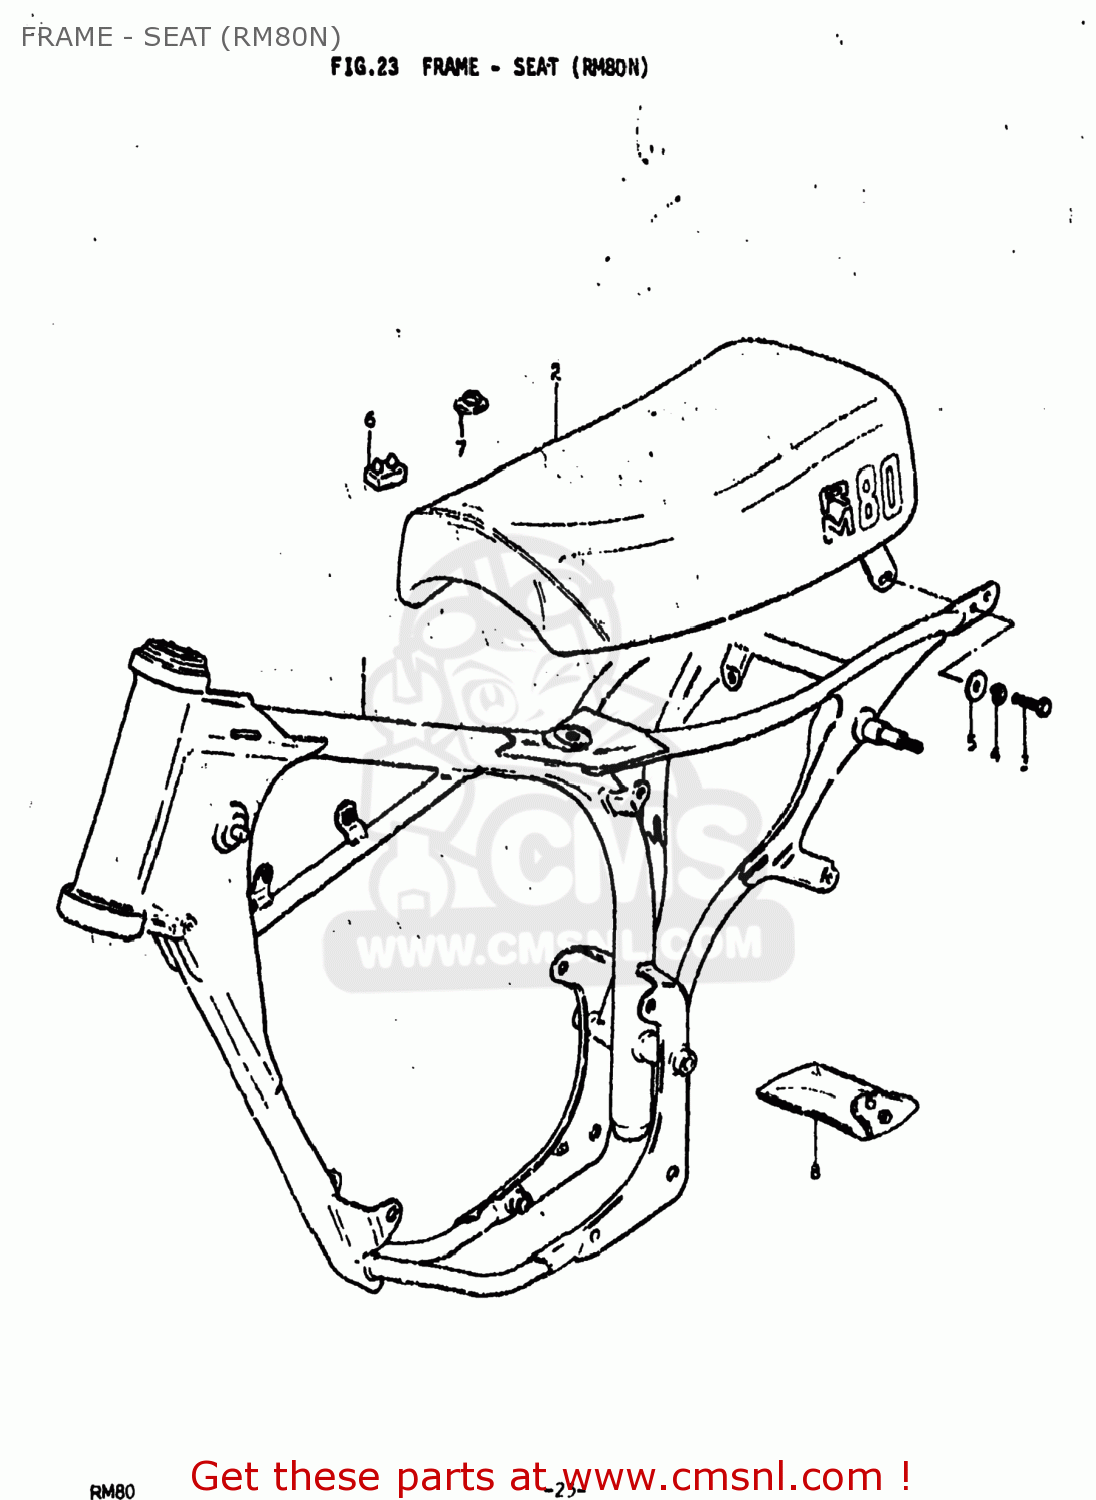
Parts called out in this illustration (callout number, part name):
1	FRAME
2	SEAT ASSEMBLY
3	BOLT, UPPER
4	LOCK WASHER
5	WASHER(6.5X18X1)
6	CUSHION
7	CUSHION
8	TOOL SET
